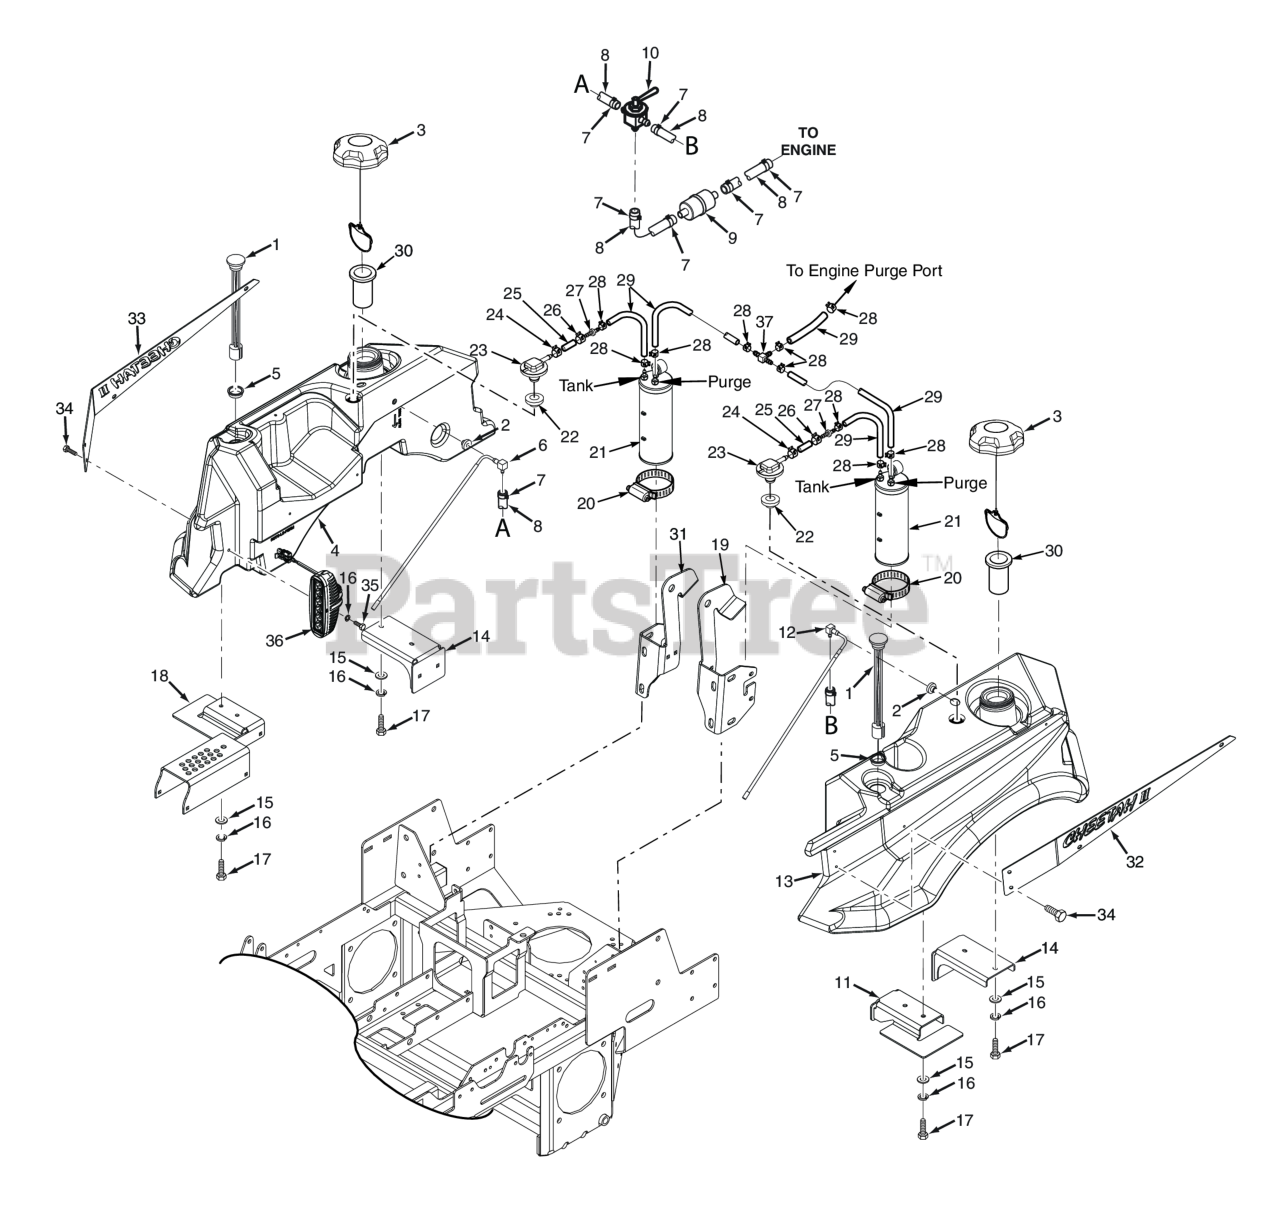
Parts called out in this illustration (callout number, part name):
1	Fuel Gauge Assembly
2	Bushing, 0.56" Dia. Viton
3	Fuel Cap w/ Tether (E.P.A.)
4	Fuel Tank Assembly, RH
5	Grommet, Fuel Gauge
6	Fuel Tube Assembly
7	Clamp, Fuel Hose 1/4" Hose I.D.
8	Fuel Hose, 1/4" I.D. Non-Perm (791DFI Fuel Return) - Order by Inch
9	Fuel Filter
10	Valve, Fuel Shut-Off
11	Mounting Bracket, Fuel Tank Front
12	Fuel Tube Assembly, LH
13	Fuel Tank Assembly, LH
14	Mounting Bracket, Fuel Tank Rear
15	Flatwasher, 5/16-.375 x .875 x .083 (35BV & 37BV-EFI)
16	Lockwasher, 5/16 (.317 x .586 x .078) Helical Spring
17	BOLT, SERRATED FLANGE HEX HEAD 5/16-18 X 3/4"
18	Adjustment Bracket, Upper Cut Height (Scag Gold)
19	ROPS Mount, LH, 29CV-EFI
20	Clamp, 3-1/2" Max. Dia.
21	Carbon Canister - SVR-52V / SVR-61V
22	Grommet, Viton,
23	Remote Vent, No Valve
24	CLAMP, FUEL HOSE(KAWASAKI ONLY)
25	Hose, 1/4" Vapor Recovery (order by inch)
26	CLAMP, FUEL HOSE(KAWASAKI ONLY)
27	Mender, 1/4 x 3/16 w/0.02 Hole
28	Clamp, Vapor Recovery Hose 3/16"
29	Hose, Vapor Recovery 3/16" (order by inch)
30	Tube, Fuel Tank Insert - 4"
31	ROPS Mount, RH, 29CV-EFI
32	Plate, LH Fuel Tank
33	Plate, RH Fuel Tank
34	CAP SCREW, 1/4-20 X 1/2" SERRATED FLANGE HEX
35	SOC HD CAPSCR, 5/16-18 X .75
36	Light Assembly
37	Tee, 3/16 x 3/16 x 3/16 Union, Hose Barb
